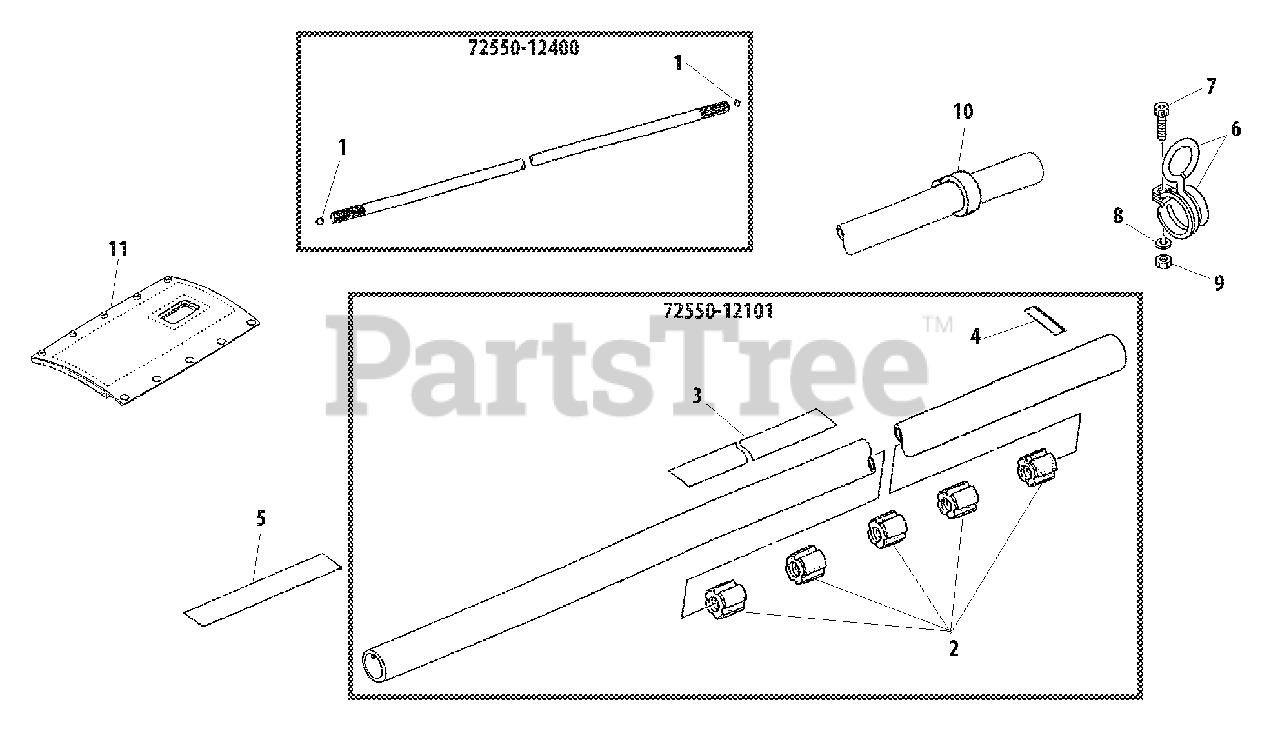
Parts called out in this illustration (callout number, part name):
1	STOPPER
2	BUSHING
3	LABEL - MODEL
4	LABEL - HANDLE LOCATION
5	LABEL - CAUTION
6	HANGER
7	SCREW - 5X12
8	LOCKWASHER - 5
10	BAND
11	PROTECTOR
72550-12101	MAIN PIPE ASSY
72550-12400	DRIVESHAFT ASSY
